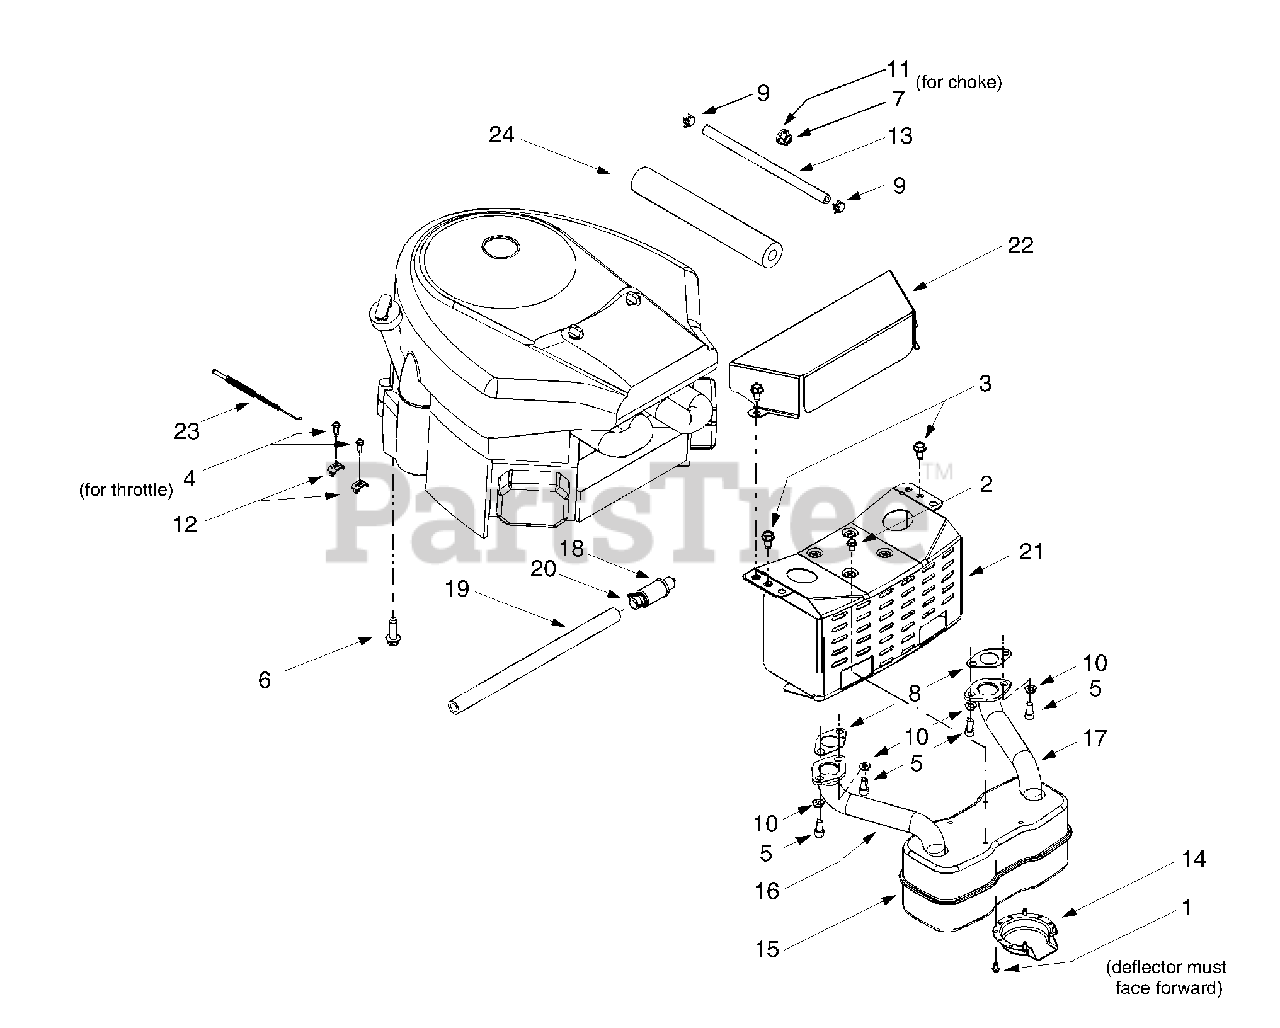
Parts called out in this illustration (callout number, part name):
1	Self Tapping Screw, #8-32 x .375
2	Self Tapping Screw, 1/4-20 x .5
3	Self Tapping Screw, 5/16-18 x .625
4	Screw, #10-32 x .625
5	Socket Cap Screw, 5/16-18 x .625
6	Self Tapping Screw, 3/8-16 x 1.25
7	Hex Nut, 3/8-16
8	Exhaust Gasket
9	Hose Clamp
10	Lock Washer, 5/16
11	Flat Washer, .406 x .875 x .059
12	Casing Clamp
13	Fuel Line Hose
14	Muffler Deflector
15	Muffler
16	RH Exhaust Pipe
17	LH Exhaust Pipe
18	Oil Drain Valve
19	Oil Drain Hose
20	Oil Drain Cap
22	Engine Heat Shield
23	Throttle Cable
24	Foam (fits over fuel line)
